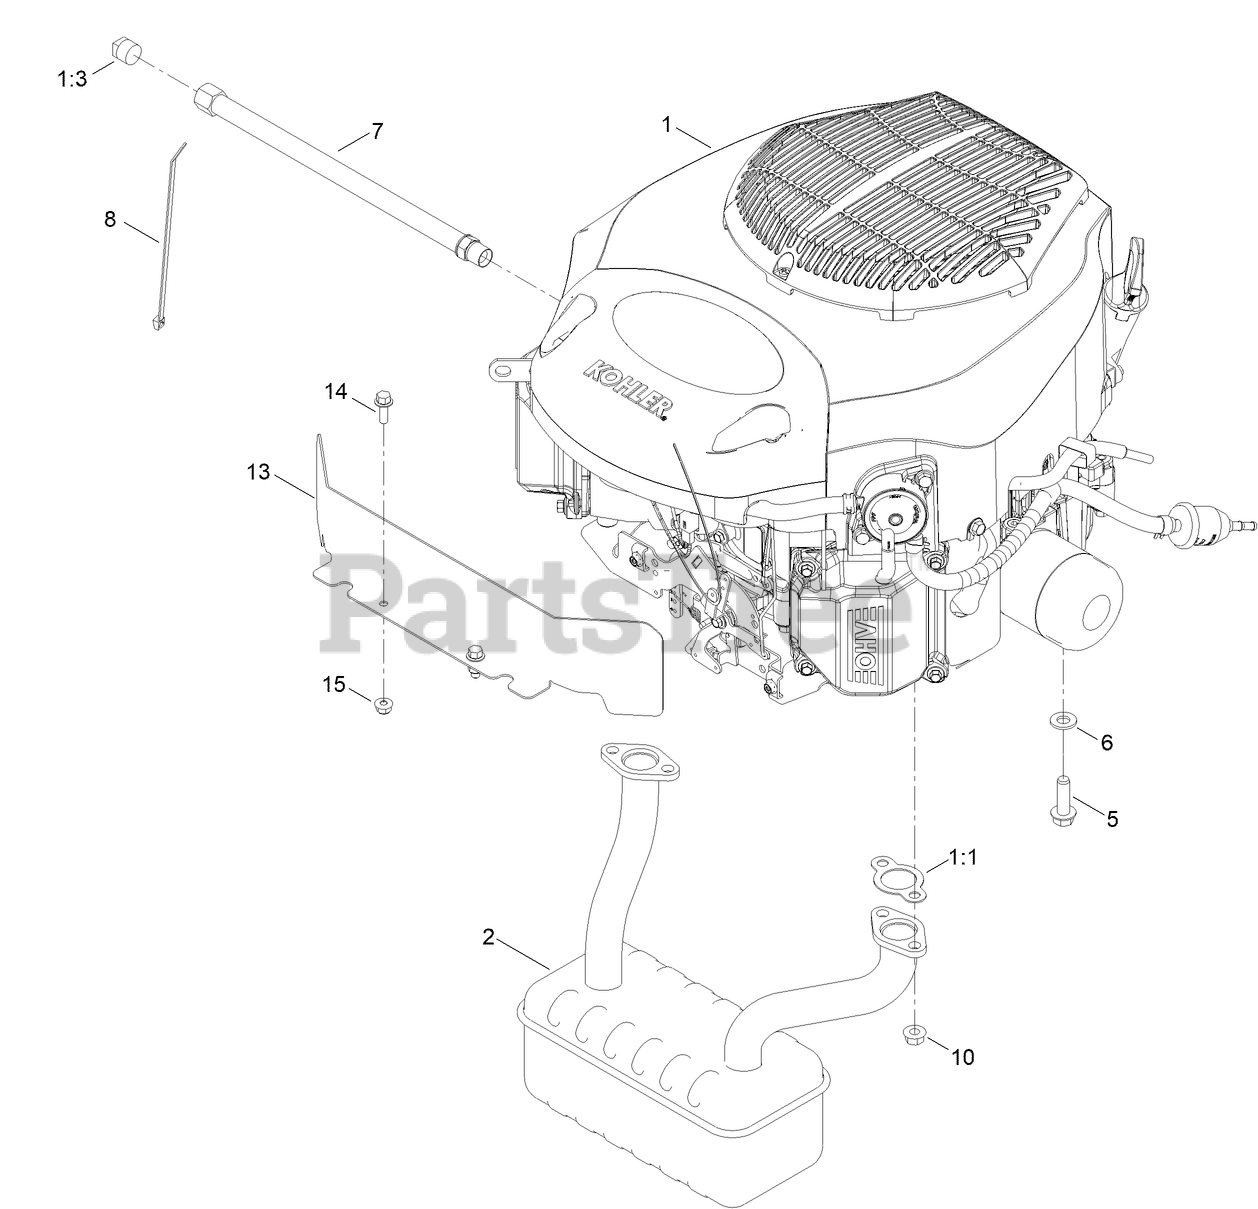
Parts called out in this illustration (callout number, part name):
2	MUFFLER
5	SCREW-THD
6	WASHER-FLAT
7	HOSE-DRAIN, OIL
8	TIE-CABLE
10	NUT-HF
13	SHIELD-HEAT
14	SCREW-HHF
15	NUT-FLANGE, NI
